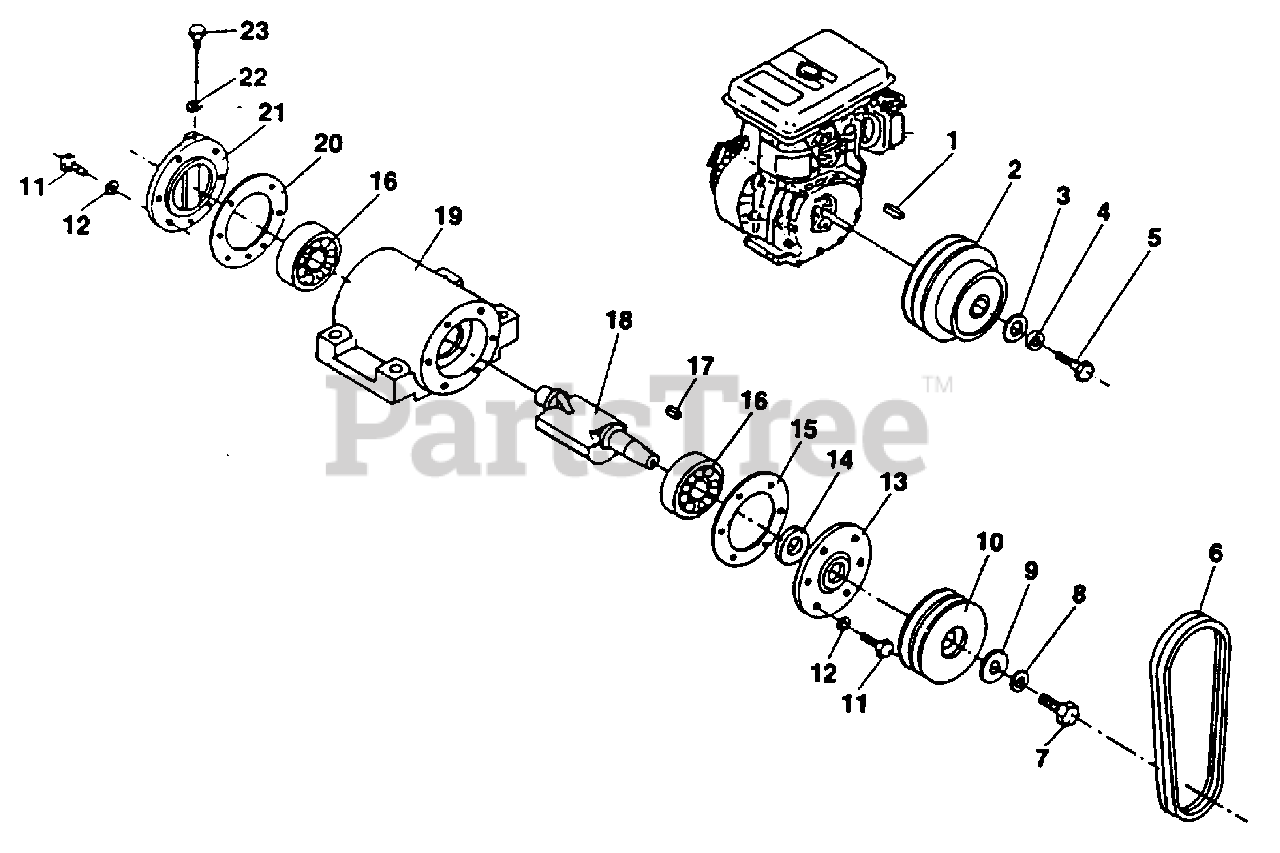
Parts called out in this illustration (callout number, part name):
1	KEY- Parallel
2	CLUTCH- Centrifugal
3	WASHER- Plate (3/8")
4	WASHER- Spring (3/8")
5	BOLT- Hex (3/8 x 1 1/2")
7	BOLT- Hex (m14 x 30)
8	WASHER- Spring (m14)
9	WASHER- Plate (m14)
10	PULLEY- V
11	BOLT- Hex (m8 x 20)
12	WASHER- Spring (m8)
13	HOLDER- Bearing
14	SEAL- Oil
17	KEY- Parallel (12 x 8 x 25)
18	UNIT- Vibration
19	CASE-Vibration Unit
21	HOLDER- Bearing
22	WASHER- Spring (m16)
23	GAUGE- Oil level
